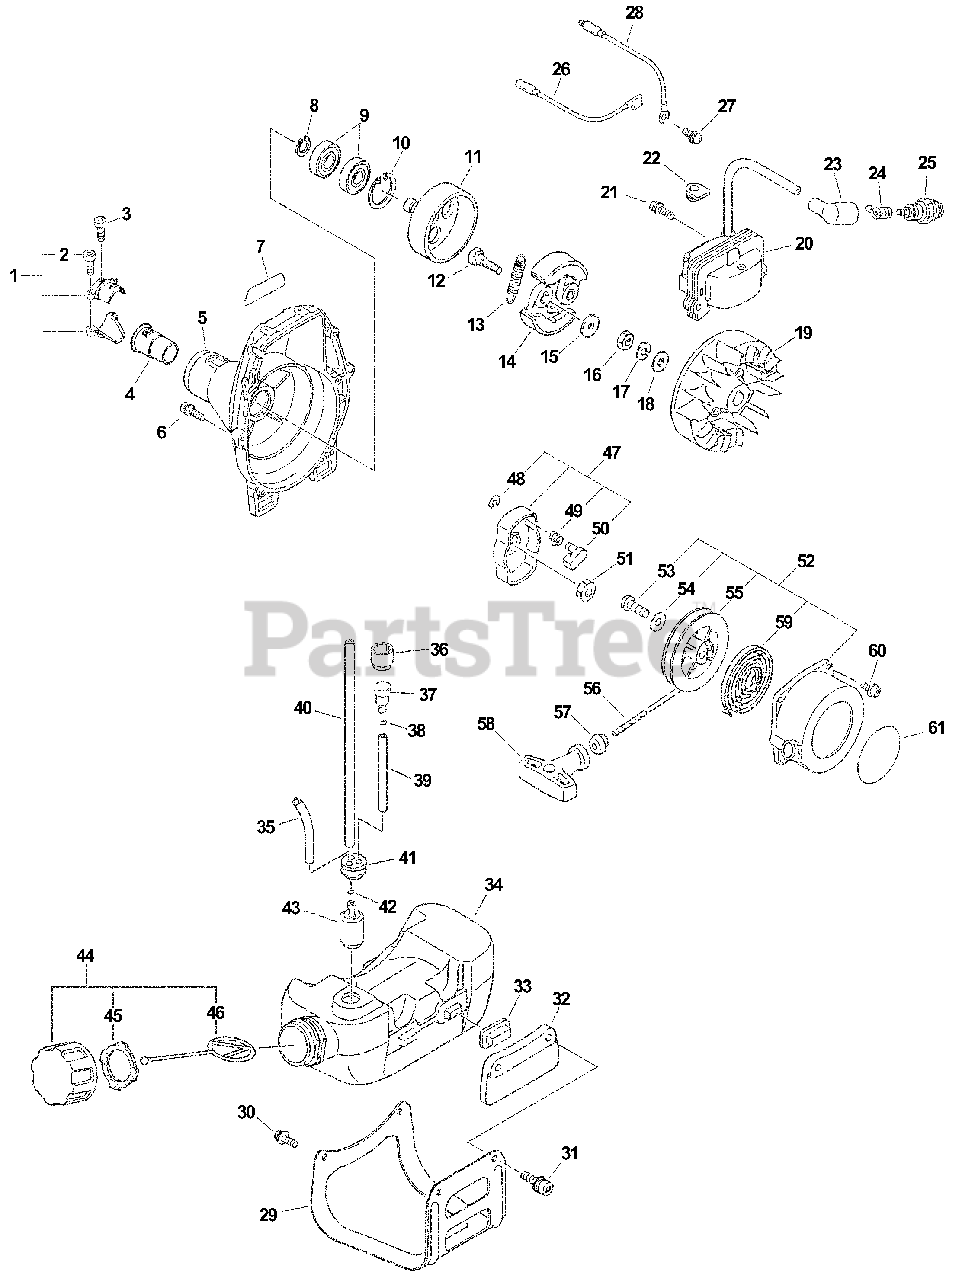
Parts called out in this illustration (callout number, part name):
1	HOLDER KIT
2	SCREW - 5X25
3	SCREW - 5X12
5	CASE, FAN
6	SCREW - 5X20
7	LABEL - MODEL SRM-340
8	RING, RETAINING - 12
9	BEARING, BALL - 6001
10	RING, RETAINING - 28
11	DRUM, CLUTCH
12	BOLT, CLUTCH
13	SPRING, CLUTCH
14	SHOE, CLUTCH
15	WASHER - 6
17	LOCKWASHER - 8
18	WASHER - 8
19	FLYWHEEL
20	COIL, IGNITION
21	SCREW - 5X20
23	CAP, SPARK PLUG
24	TERMINAL, SPARK PLUG CAP
25	SPARK PLUG -- BPM-7A
25	SPARK PLUG -- BPMR-7A
26	LEAD - IGNITION
27	SCREW - 5X10
28	LEAD - GROUND
29	GUARD, FUEL TANK
30	SCREW - 5X12
31	SCREW - 5X20
32	BRACKET, FUEL TANK
33	CUSHION, FUEL TANK
34	TANK, FUEL
35	PIPE - 3X6X90 -- CLEAR
36	COVER, VENT
37	VENT, FUEL TANK
38	CLIP - 5.5
39	PIPE - 3X5X50 -- BLACK
40	PIPE - 3X5X180 -- BLACK
41	GROMMET
42	CLIP - 6
43	FILTER, FUEL
44	CAP ASSY - ORANGE
45	GASKET, CAP
46	CONNECTOR, CAP
47	STARTER PAWL ASSY
48	RING, RETAINING - 4
49	SPRING, RETURN
50	PAWL, STARTER
52	STARTER ASSY
55	REEL, ROPE
56	ROPE, STARTER - 4X880
57	GUIDE, ROPE
58	GRIP, STARTER
59	SPRING, REWIND
60	SCREW - 4X14
61	LABEL - ECHO
